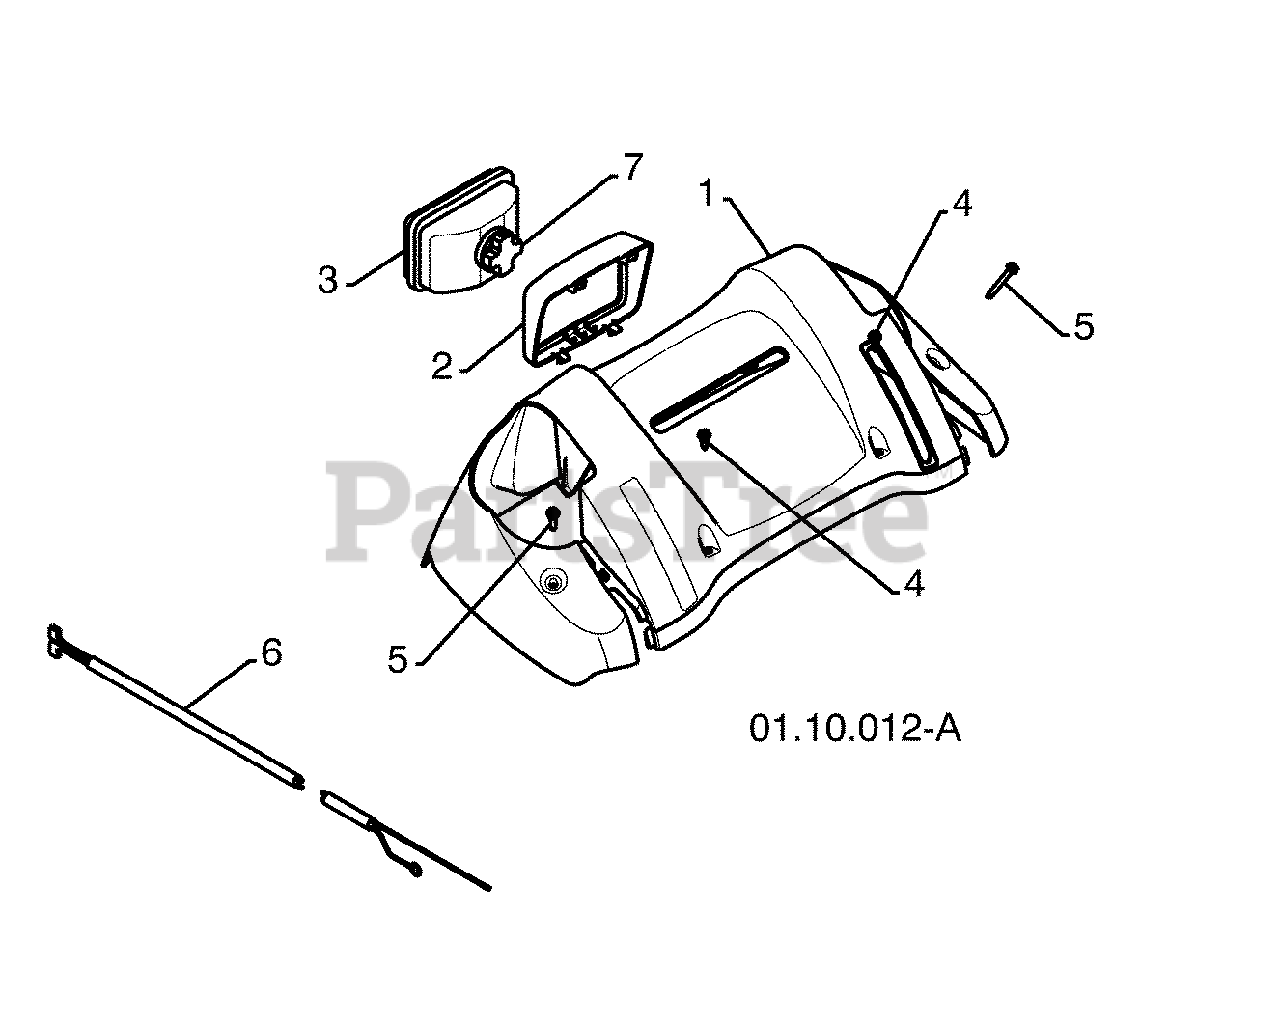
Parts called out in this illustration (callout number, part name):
1	CONSOLE PANEL GRAY
2	HEADLIGHT BEZEL GRAY
3	FLOOD HEADLIGHT
4	SHOULDER SCREW 10-24 X .625
5	SCREW 10-24 X 1.25
6	WIRE HARNESS
